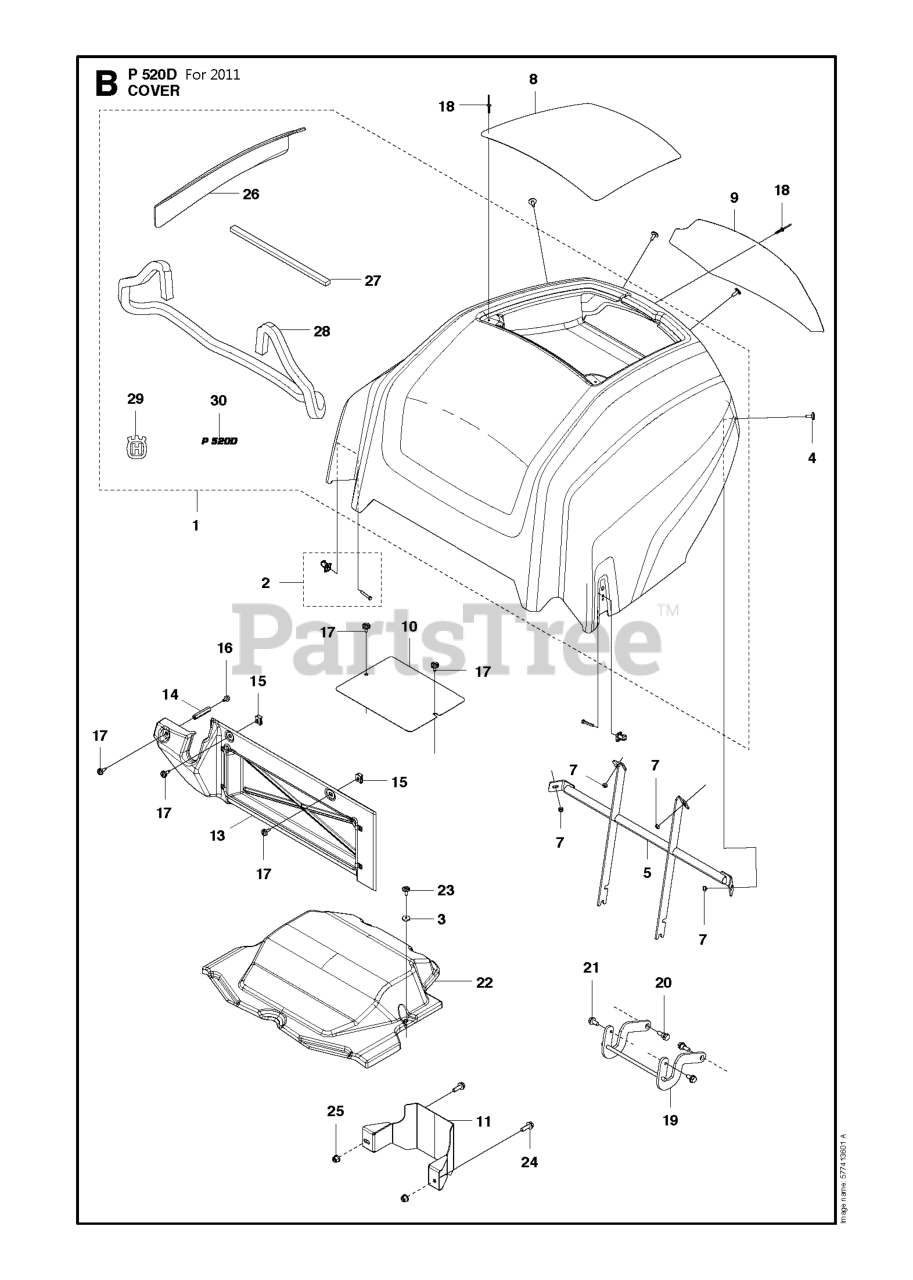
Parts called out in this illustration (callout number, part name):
7	NUT FLANGE
20	NUT FLANGE
24	BOLT
25	NUT FLANGE
29	DECAL HUSQVARNA CROWN HEIGHT 5
